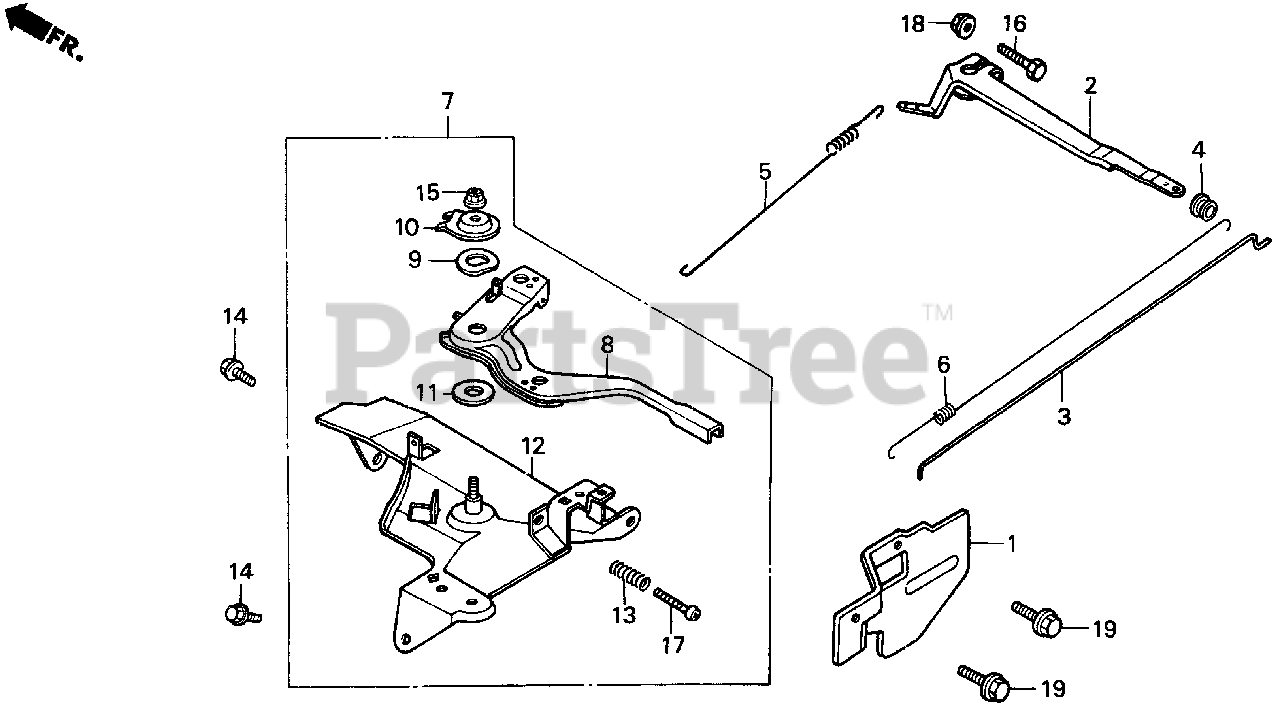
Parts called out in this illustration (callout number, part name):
1	SPRING, CONTROL LEVER
2	ARM, GOVERNOR
3	ROD, GOVERNOR
4	COLLAR, GOVERNOR ROD
5	SPRING, GOVERNOR
6	SPRING, THROTTLE RETURN
7	CONTROL ASSY.
8	LEVER, CONTROL
9	SPRING, LEVER
10	WASHER, CONTROL LEVER
11	SPACER, CONTROL LEVER
12	BASE, CONTROL
13	SPRING, CONTROL ADJUSTING
14	BOLT, FLANGE (6X12) (CT200)
15	NUT, SELF-LOCK (6MM)
16	BOLT, GOVERNOR ARM
16	BOLT, HEX. (6X22)
17	SCREW, PAN (5X28)
18	NUT, FLANGE (6MM)
19	BOLT, FLANGE (6X10)
